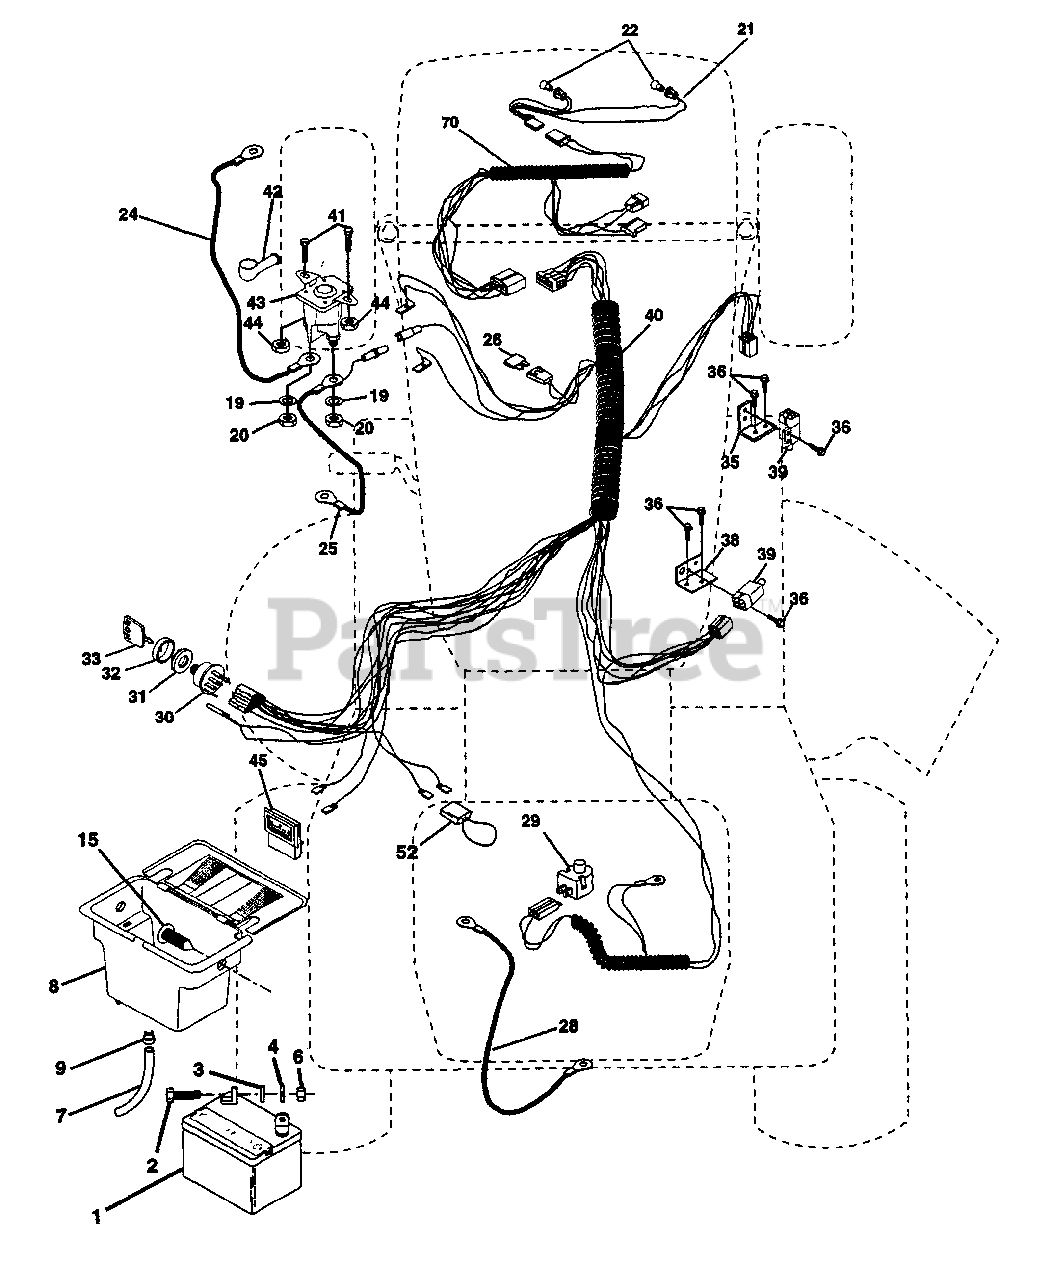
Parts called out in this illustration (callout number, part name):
1	Battery 12 Volt 25 AMP
2	Bolt Hex Hd 1/4-20unc X 3/4
3	Washer 9/32 X 5/8 X 16 Ga.
4	Washer Lock Hvy Helical 1/4
6	Nut Fin Hex 1/4-20 Unc
7	Tube Plastic 12"
8	Case Battery Hng Mech W/lid W/Holes W.Brty
9	Clamp Hose Olive
15	Fastner, Snap-In
19	Washer Lock 1/4
20	Nut Jam Hex 1/4-20 Unc
21	Harness Asm Light W/4152j
22	Bulb Light #1156
24	Cable Battery 6 Ga 11" red
25	Cable Battery 6 Ga red w/16 wire
26	Fuse 30 AMP Auto Green
28	Cable Ground 6 Ga 12" black
29	Switch Plunger Nc Gray
30	Switch ign 4 pos w/lights
31	Nut ignition
32	Cover Sw Ignition
33	Key Ign Modleded Generic
35	Bracket Switch Clutch
36	Screw Tap Hex #10-24unc X 1/2
38	Bracket, Switch, Interlock
39	Switch Intlk Clutch Red 4 Term
40	Harness Ign Hm LT PL Mech
41	Bolt Blk Fin Hex 1/4 - 20 x 1/2 UNC
42	Cover Terminal Red
43	Solenoid
44	Nut Keps Hex 1/4-20 Unc
45	Ammeter Rectangular
52	Protection Wire Loop
70	Harness, Eng.
